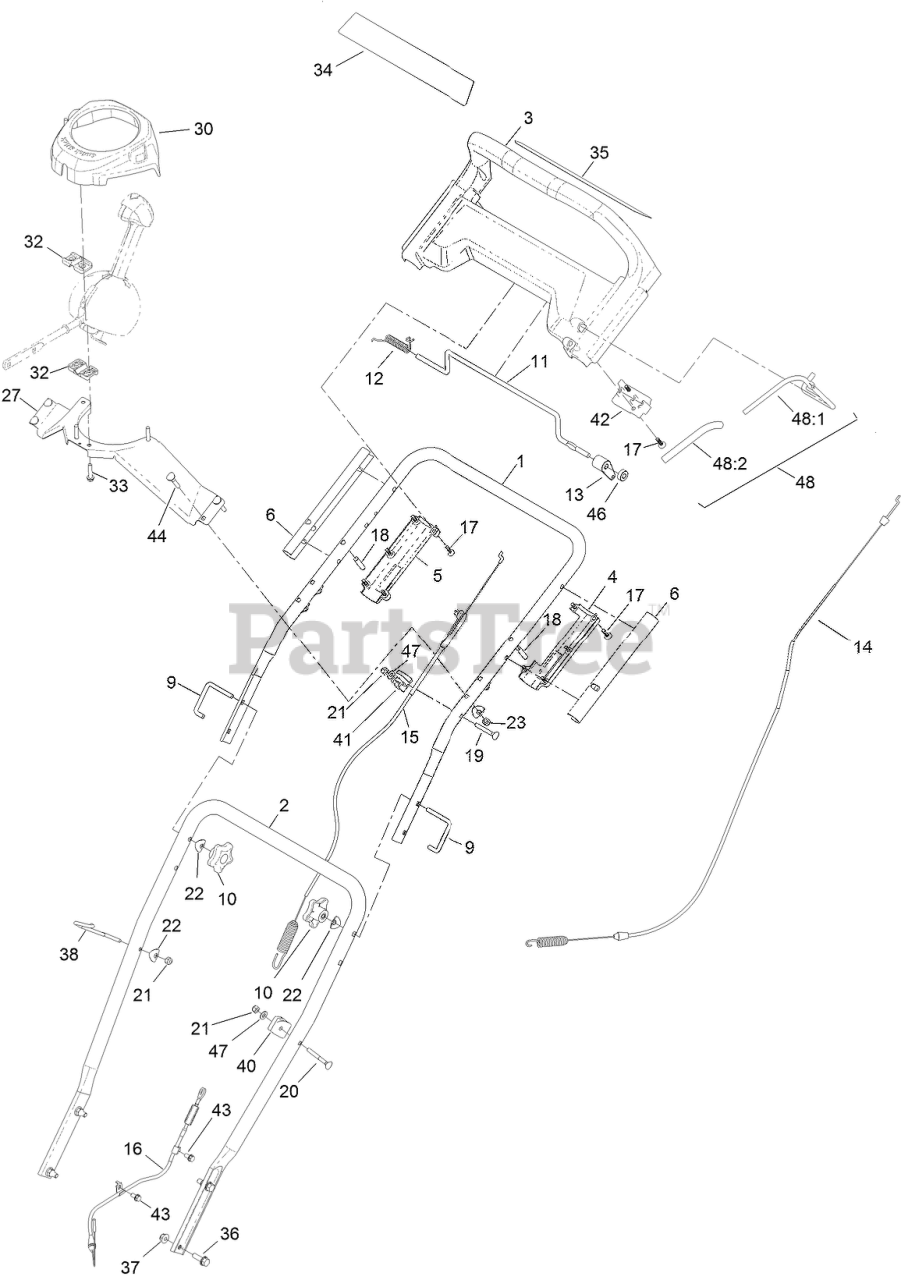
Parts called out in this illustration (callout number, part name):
1	HANDLE-UPPER
2	HANDLE-LOWER
3	HANDLE
4	HANDLE-BOTTOM, LH
5	HANDLE-BOTTOM, RH
6	SLEEVE HANDLE
9	LOCK-HANDLE
10	KNOB-HANDLE
11	BAR-CONTROL, TRACTION
12	Spring-Torsion
13	LEVER-TRACTION
14	CABLE-TRANSMISSION
15	CABLE-ROTOR, UPPER
16	CABLE-ROTOR, LOWER
18	PIN-DOWEL
19	SCREW
20	SCREW-HANDLE
21	NUT-LOCK, NI
22	WASHER
23	NUT-LOCK, NI
27	BRACKET-CHUTE, CONTROL
30	COVER TOP
32	SUPPORT-ROD
33	SCREW-PLASTITE
34	DECAL-DISPLAY
35	DECAL-CONTROL, PANEL
36	SCREW-HHF
37	NUT-HF, NI
38	GUIDE-ROPE
40	ANCHOR-CABLE, UPPER
41	CABLE-GUIDE
42	BAIL-MOUNT
43	SCREW-HWH
44	SCREW-HANDLE
46	SPACER
47	WASHER-FLAT
48	BAIL ASM
48:1	BAIL-AUGER
48:2	COVER-BAIL
